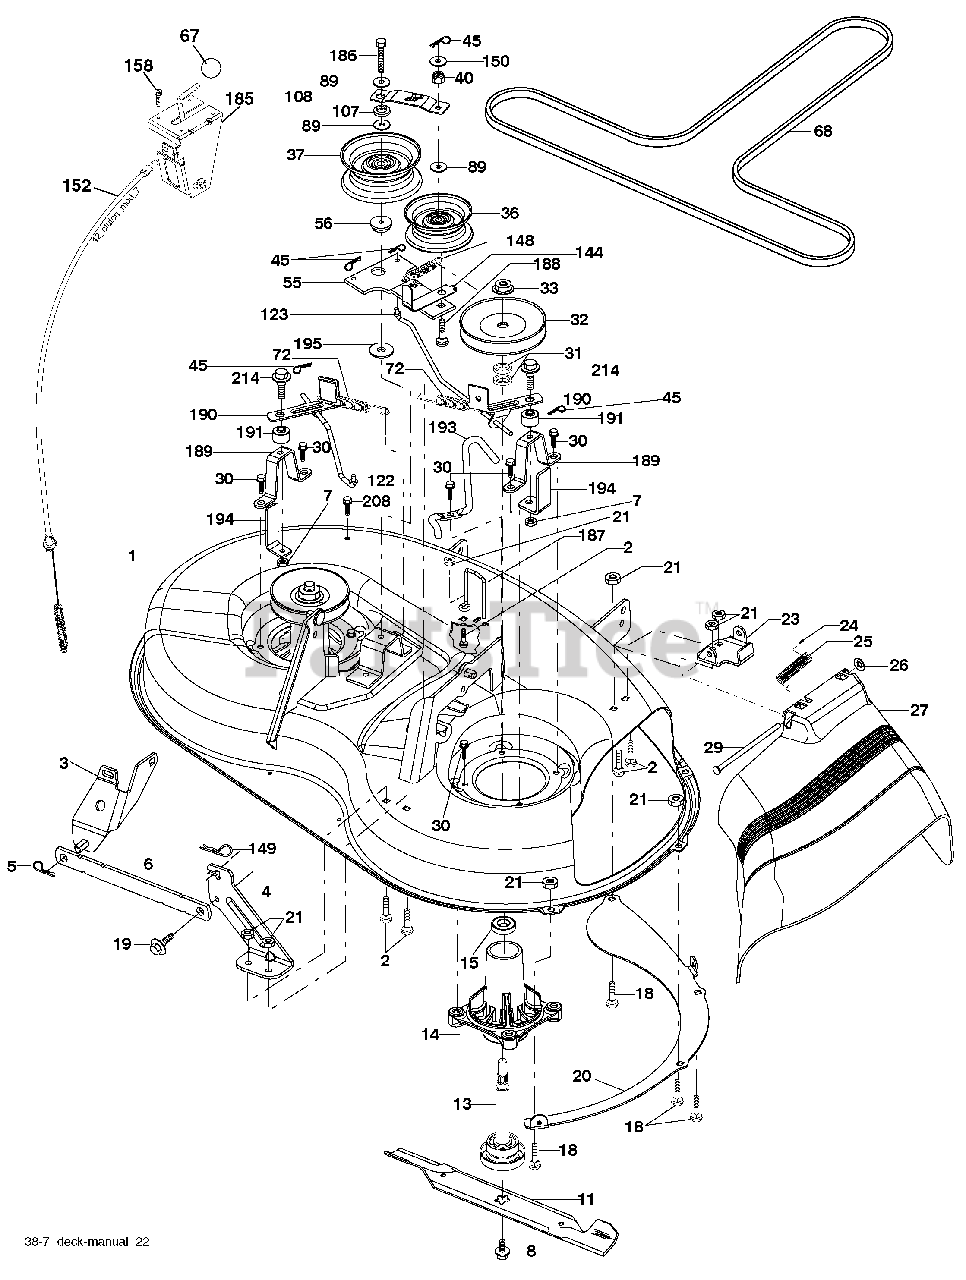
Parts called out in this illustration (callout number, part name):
1	Mower Housing Assembly
2	Bolt Carriage 5/16-18 x 3/4
3	Bracket Asm Fr. Sway Bar
4	Bracket Deck Sway Bar 38"/42"
5	Retainer Spring
6	Bar Sway Deck
7	Nut Lock Hex w/Ins. 5/16-18 unc
8	Bolt 3/8-24 x 1.25 Gr. 8
11	Blade Mower
11	Blade 38" Hi-Lift
13	Shaft Assembly, Mandrel, Vented
14	Housing, Mandrel, Vented
15	Bearing, Ball, Mandrel
18	Bolt Rdhd. Sqnk. 5/16-18 x 5/8
19	Bolt, Shoulder
20	Baffle Vortex Front
21	Nut
23	Bracket, Mower Deflector
24	Cap, Sleeve
25	Spring, Torsion, Deflector
26	Nut, Push
27	Shield, Deflector
29	Rod, Hinge
30	Screw Thdrol.
31	Washer, Spacer
32	Pulley, Mandrel
33	Nut, Toplock
36	Pulley, Idler, Flat
37	Pulley Idler Flat
40	Nut, Crownlock 3/8-16 unc
45	Retainer Spring
55	Idler Arm Assembly
56	Spacer, Retainer
67	Knob
68	V-Belt
72	Spring Brake Return
89	Washer 13/32 x 13/16 x 11 Ga.
107	Spacer Retainer
108	Stiffener, Idler Arm
122	Rod, Brake LH
123	Rod, Brake RH
144	Keeper Belt Idler Tension
148	Spring Return Idler
149	Retainer Spring Yellow
150	Washer 9/32 x 3/4 x 10 Ga.
152	Clutch Cable 38"/46"
158	Screw Hex Thd. Cut. 1/4-20 x 1/2
185	Head Asm. Cable Clutch
186	Screw Hex Wsh. Thdrol. 3/8-16 x 2-3/4
187	Keeper Belt
188	Bolt Carriage Idler
189	Stand, Brake
190	Arm, Brake
191	Spacer, Brake
193	Keeper Belt RH Mandrel
194	Guard Brake
195	Washer
208	Screw Thdrol 3/8-16 x 1/2
214	Bolt/Washer Asm. 5/16-18
214	Brake Assembly
214	Mandrel Assembly
214	Replacement Mower, Complete
